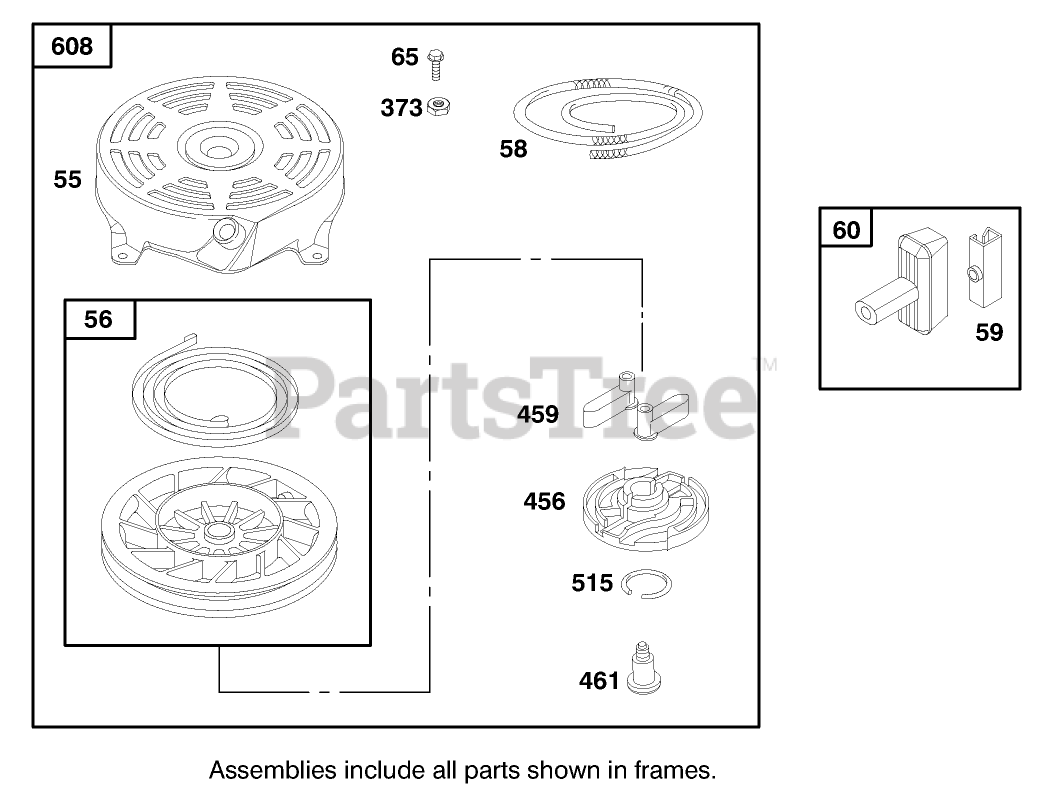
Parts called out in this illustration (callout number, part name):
56	PULLEY-STARTER, REWIND
58	ROPE-STARTER
59	INSERT-HANDLE, REWIND
65	SCREW-HH
373	NUT-HEX
456	RETAINER-STARTER, REWIND
459	PAWL-STARTER
515	SPRING-TORSION
608	REWIND ASM
